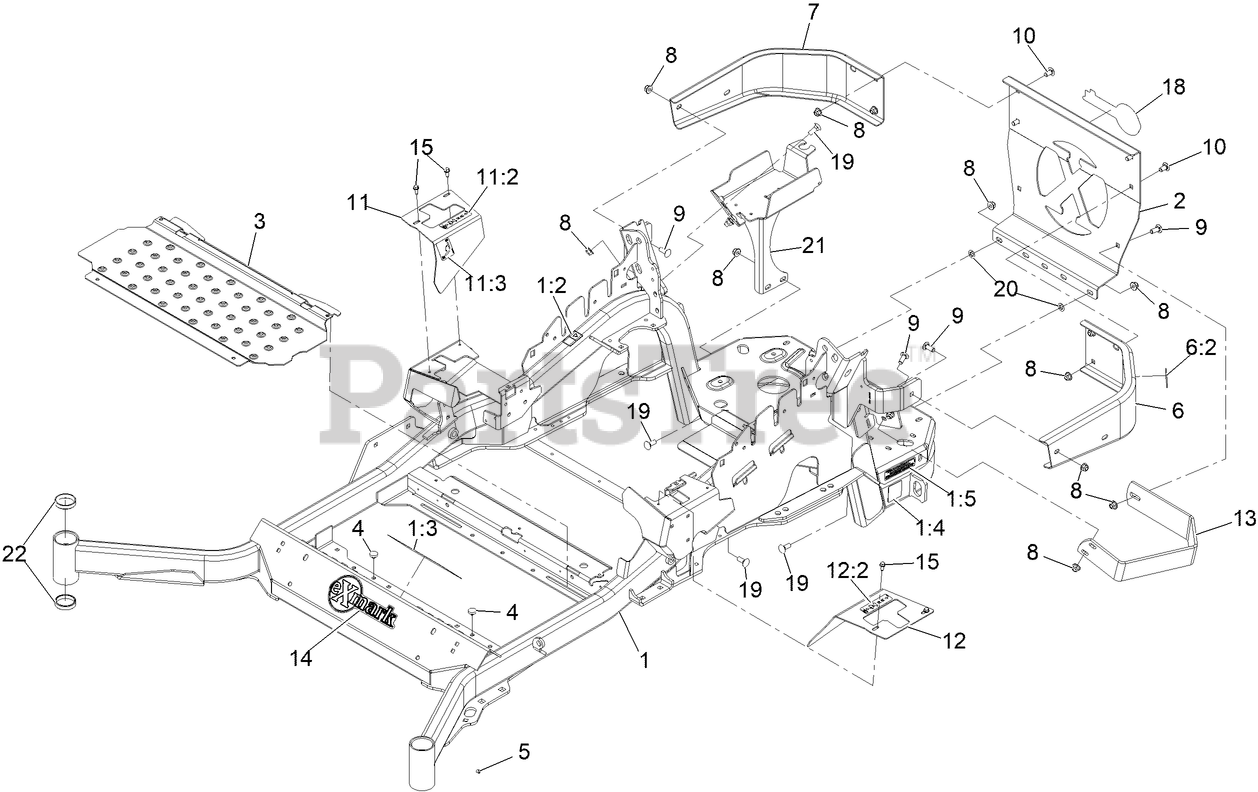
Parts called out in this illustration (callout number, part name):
1	Mainframe ASM-72 W/Decals
1:2	DECAL-ARRESTOR, SPARK
1:3	DECAL-WARNING
1:4	DECAL-HAZARD, PINCHED FINGER
1:5	DECAL-DANGER
2	PLATE,REAR GUARD
6	LH BUMPER ASM
6:2	DECAL-WARNING
7	BUMPER-RH
8	NUT-HF, NI
9	SCREW-CARR
10	SCREW-CARR
11	RH MOTION CONTROL COVER ASM
11:2	DECAL-CONTROL, MOTION
11:3	DECAL-PARK BRAKE, CE
12	LH MOTION CONTROL COVER ASM
12:2	DECAL-CONTROL, MOTION
13	GUARD-MUFFLER
14	DECAL-EXMARK
15	SCREW-HWH
18	DECAL, EXMARK LOGO
19	BOLT-CARR
20	NUT-PUSH
21	Weld-Battery Mount
22	CUP-BEARING
